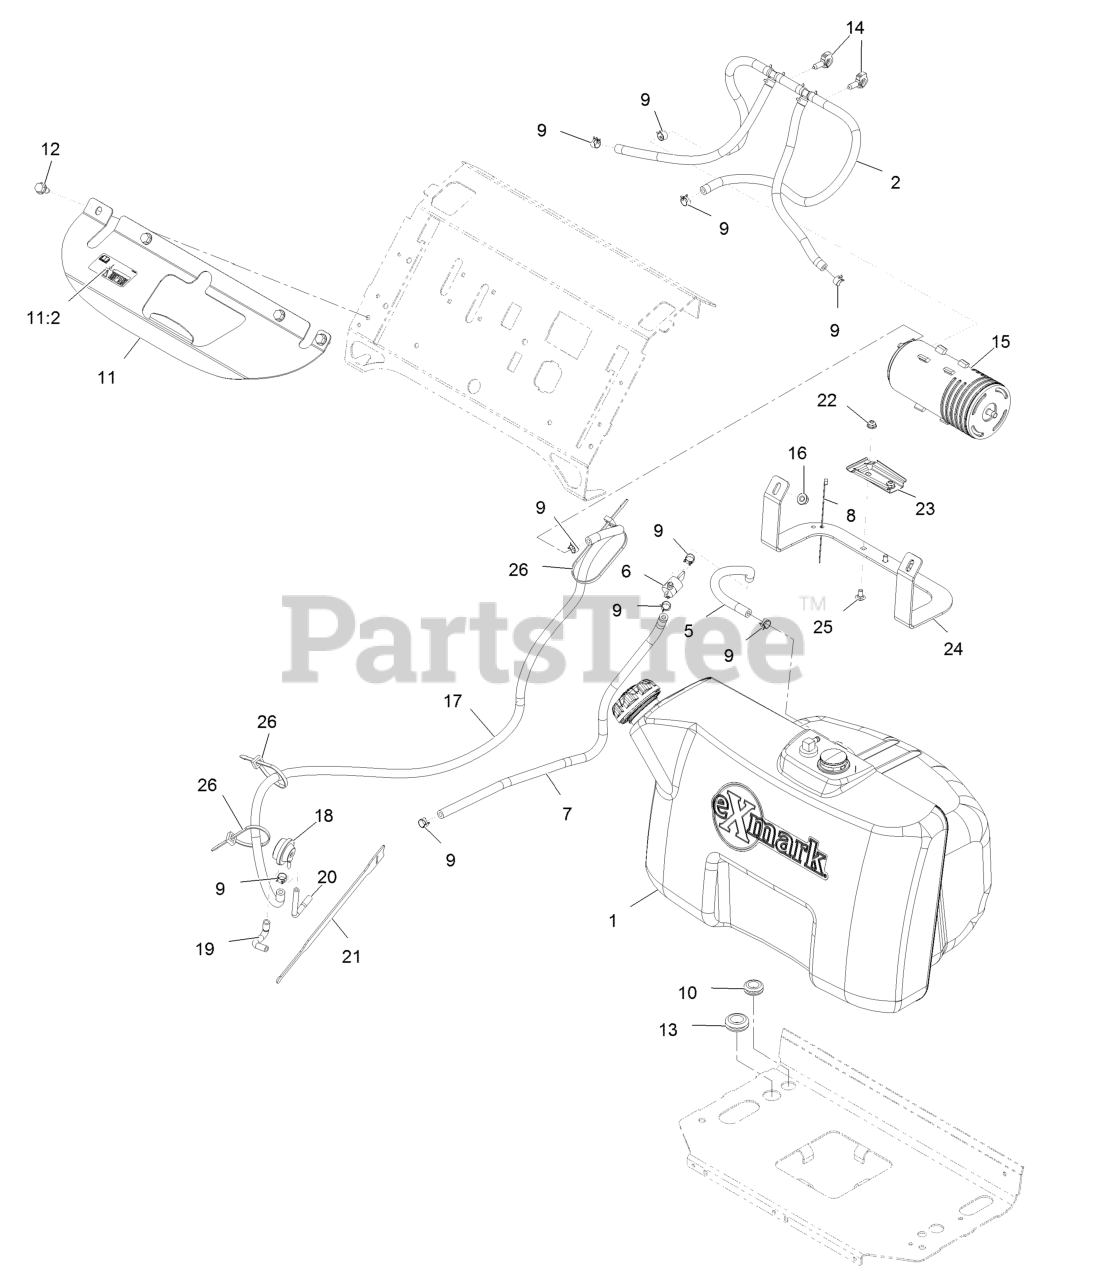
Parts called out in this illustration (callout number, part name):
1	Tank ASM-
2	Vent ASM
5	Hose-Fuel
6	Valve-Fuel
7	Hose-Fuel
8	Tie-Cable 5 1/2 (Small)
9	Clamp-Hose
10	Grommet
11	Bracket-Tank
11:2	Decal-Fill, Fuel
12	Screw-HWH 5/16-18 X 3/4 Tf
13	Grommet
14	Clip-Harness
15	Canister-Carbon, 800Cc
16	Nut-Nyloc 5/16-18 Flg
17	Hose-Fuel
18	Valve-Control, Vacuum
19	Hose-Vent, Formed
20	Hose-Vent, Formed
21	Strap-Velcro, Cable Tie
22	Nut-Nyloc 1/4-20 Flg
23	Bracket-Canister, Carbon
24	Bracket-Canister Mounting
25	Bolt-Carriage 1/4-20 X 1/2 Short Neck
26	Tie-Cable
